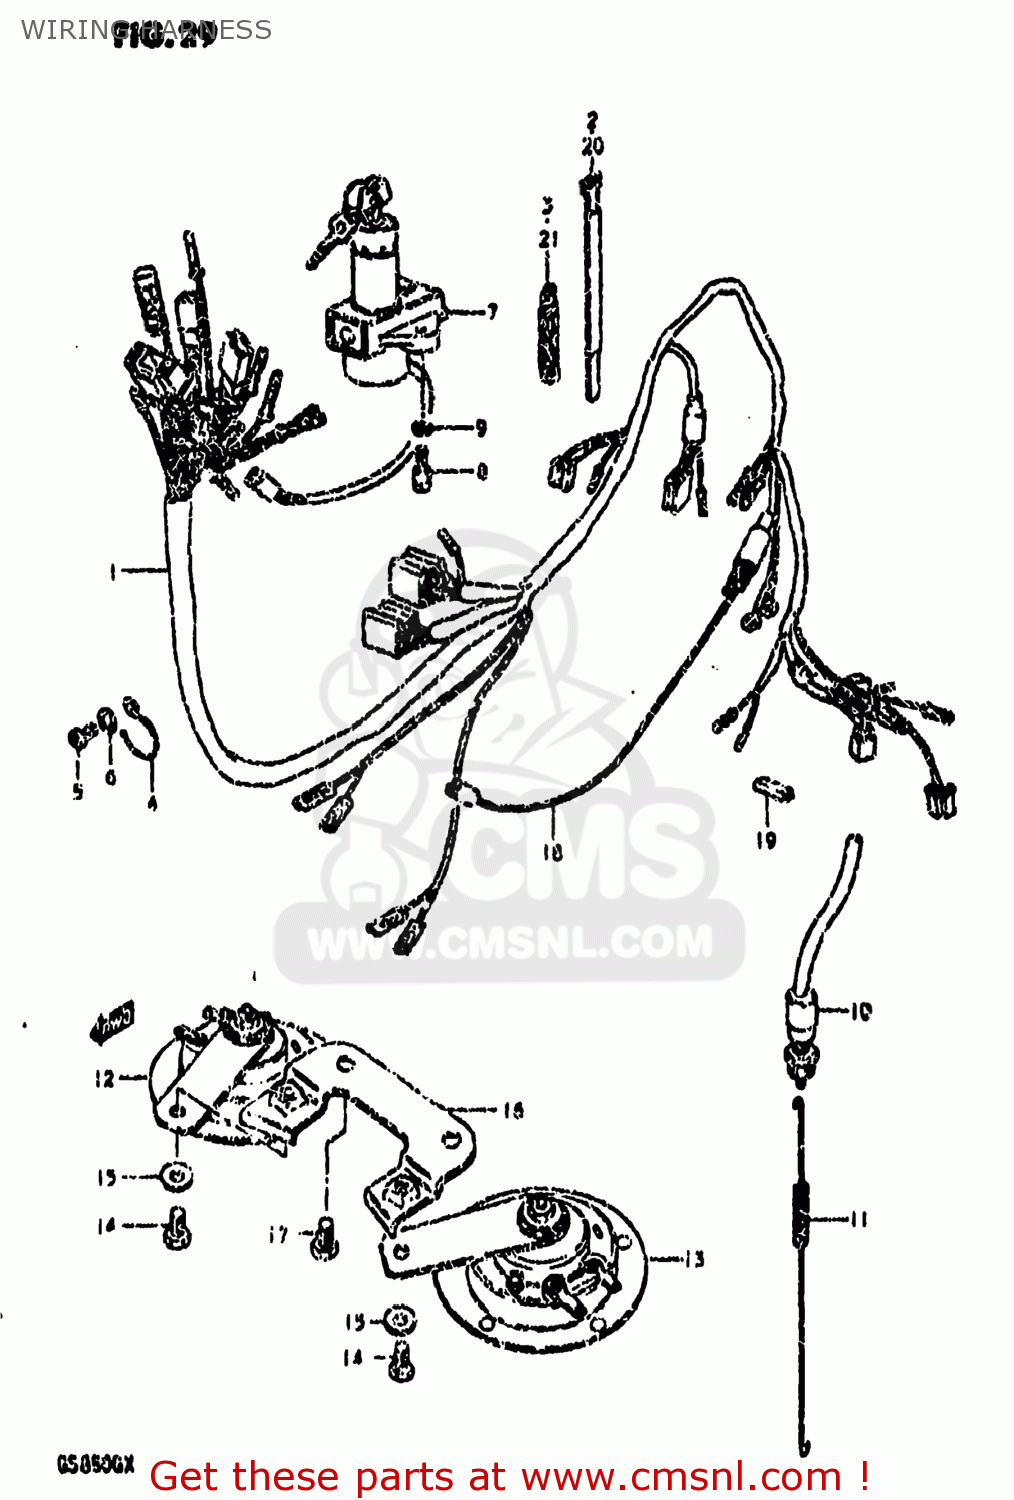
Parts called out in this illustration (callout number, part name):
1	HARNESS,WIRING
2	CLAMP
3	CLAMP
4	GUIDE,WIRING HARNESS
5	SCREW 6X12
6	WASHER
7	LOCK ASSEMBLY,STEERING
8	BOLT
9	LOCK WASHER
10	SWITCH ASSEMBLY,STOP LAMP
11	SPRING
12	HORN ASSEMBLY,LOW PITCH
13	HORN ASSEMBLY,HIGH PITCH
14	BOLT
15	WASHER
16	BRACKET,HORN
17	BOLT 8X12
18	WIRE
19	PROTECTOR,WIRING HARNESS
20	CLAMP(L:120)
21	CLAMP
